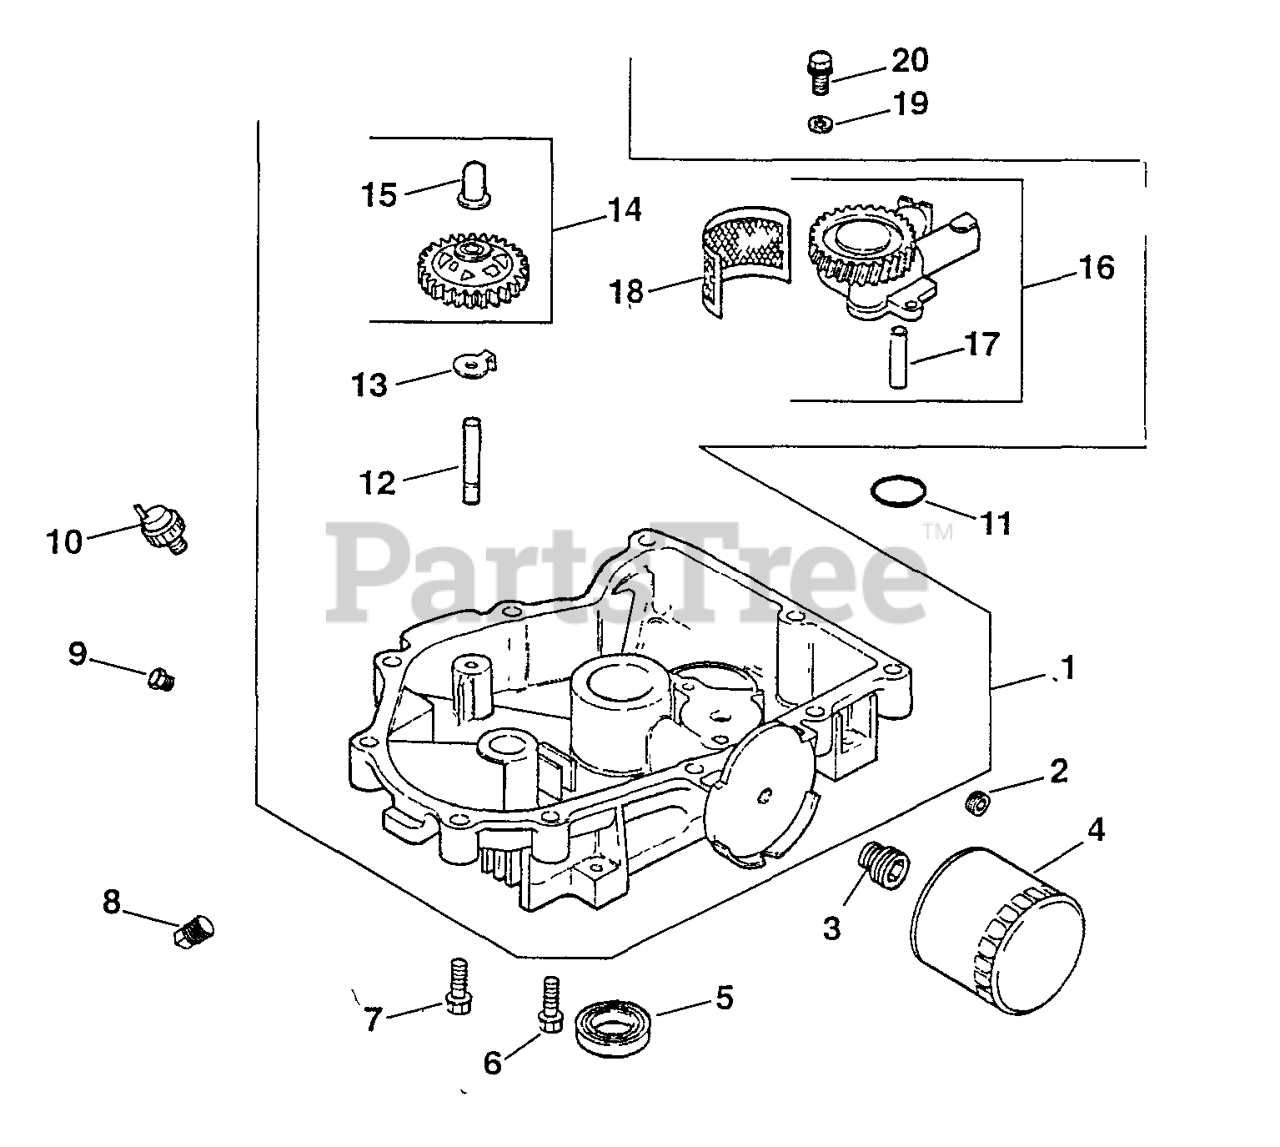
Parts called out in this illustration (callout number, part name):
1	Oil Pan Assembly
2	Plug, Allen Hd. 3/8"
4	Filter, Oil
5	Seal, Oil (Pto End)
6	Screw, Hex. Flange M8x1.25x45
7	Screw, Hex. Flange M8x1.25x45
8	Plug, Sq. Hd. Solid 3/8" N.P.T.F.
10	Switch, Oil Pressure
12	Shaft, Governor Gear
13	Tab, Locking
14	Kit, Governor Gear W/ Pin
16	Oil Pump Assembly (13 Mm)
16	Oil Pump Assembly (17 Mm)
17	Tube, Oil Pickup
18	RING-HANDLE LOCK
19	Washer, Plain 6 Mm
20	Screw, Hex. Flange M6x1.0x25
